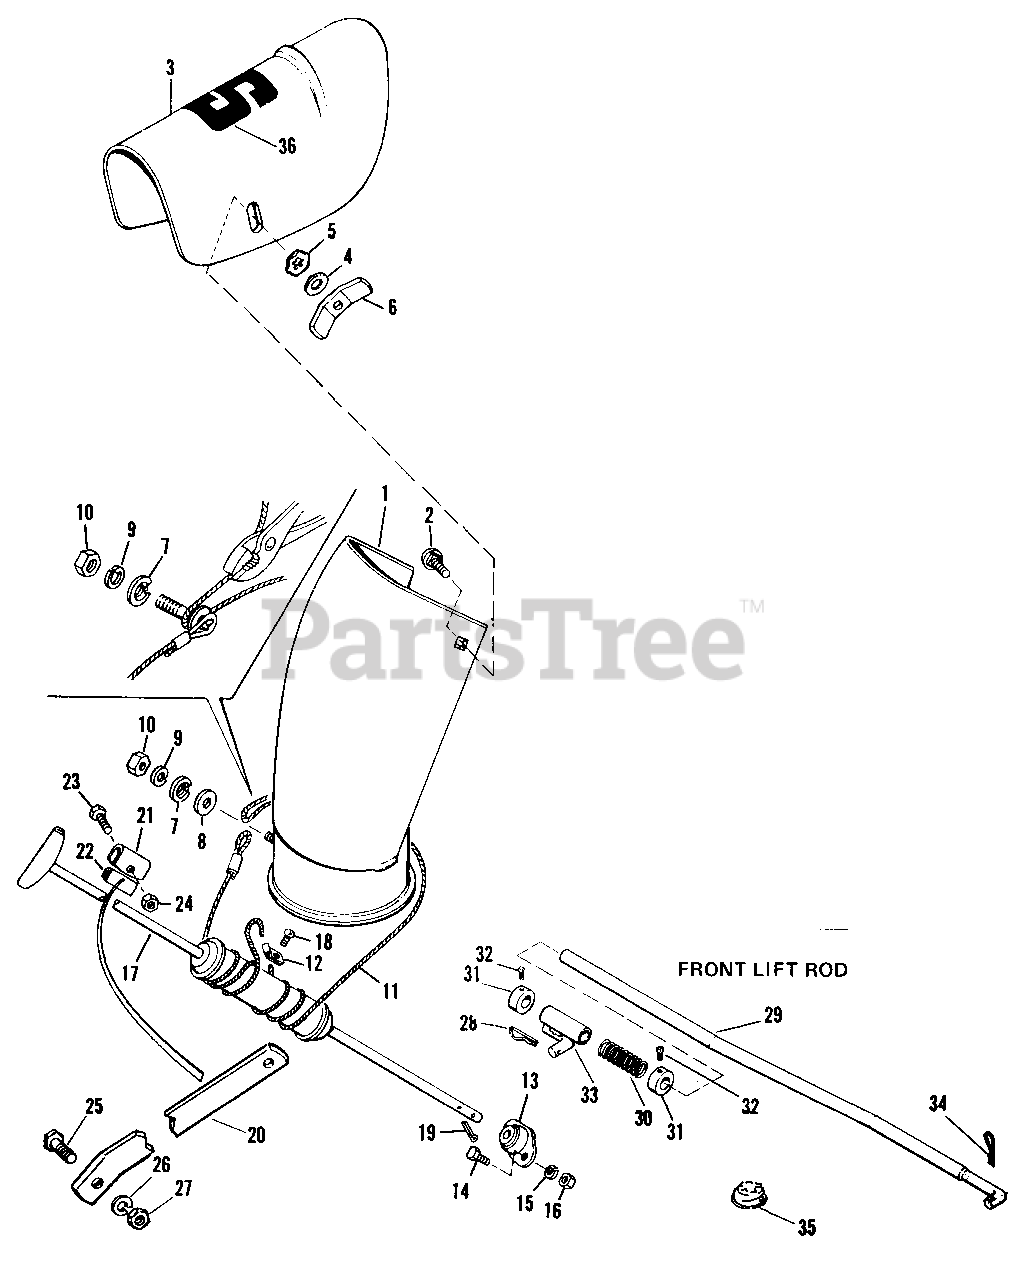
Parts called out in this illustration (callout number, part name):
1	Spout Assembly 10
2	Carriage Bolt, 5/16"-18 x 3/4"
3	Spout Extension
4	Plain Washer, 3/8"
5	Lock Washer
6	NUT, Wing, 5/16-18
8	Plain Washer, 1/4"
9	Lock Washer, 5/16"
10	Hex Nut, Full, 5/16"-18
11	Cable Assembly
14	Hex Capscrew 1/4"-20 x 5/8"
15	Lock Washer, 1/4"
16	Hex Nut, Full, 1/4"-20
17	Spout Control Assembly
18	Taptite Screw, 1/4"-20 x 3/8"
19	Cotter Pin, 3/32" x 5/8"
20	Rod Guide Support
22	Guide Liner
23	Hex Capscrew, 5/16"-18 x 1-1/4"
24	Hex Nut, Full, Lock, 5/16"-18
25	Hex Capscrew, 3/8"-16 x 1-1/4"
26	Lock Washer, 3/8"
27	Hex Nut, Full, 3/8"-16
28	Spring Clip
29	Front Lift Arm
31	Collar
32	Set Screw, 5/16"-18 x 3/8"
33	Rod Guide Assembly
34	Spring Clip
35	Winterized Fuel Cap
